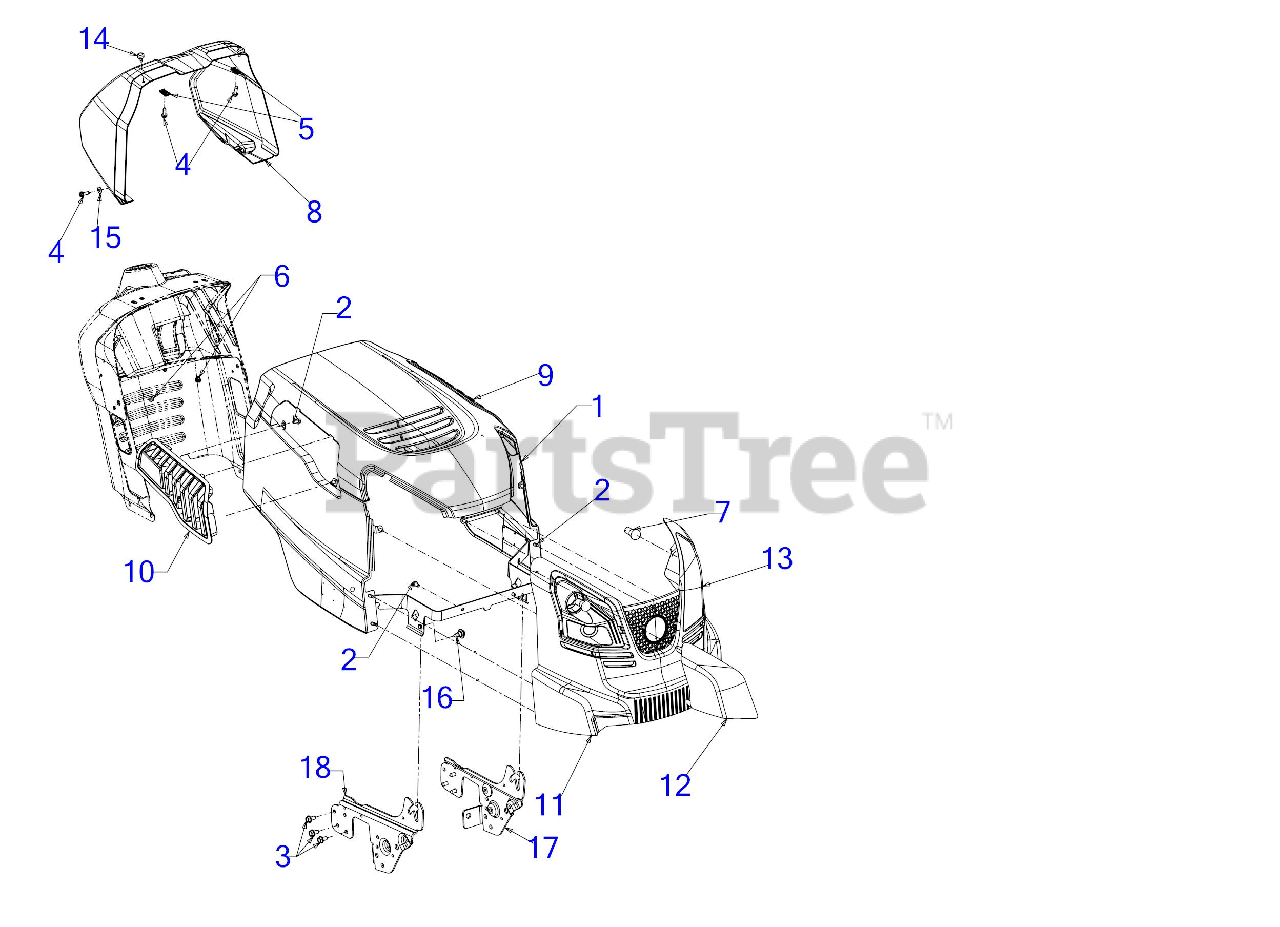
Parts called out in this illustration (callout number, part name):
2	HEX SCREW 1/4-15 x .50
3	SCREW 5/16-18 x .750
4	SCREW 1/4-20 x .750
5	SPEED NUT
6	FLANGE LOCK NUT
7	MINIATUURE BULB 12V
8	DASH COLLER
9	HOOD SCOOP (LH)
10	HOOD SCOOP (RH)
11	FRONT GRILL
12	LENS (RH)
13	LENS (LH)
14	BUMPER, .62 DIA x .3
15	FLAT WASHER
16	SHOULDER SCREW .43X.29X5/16-18 TT
